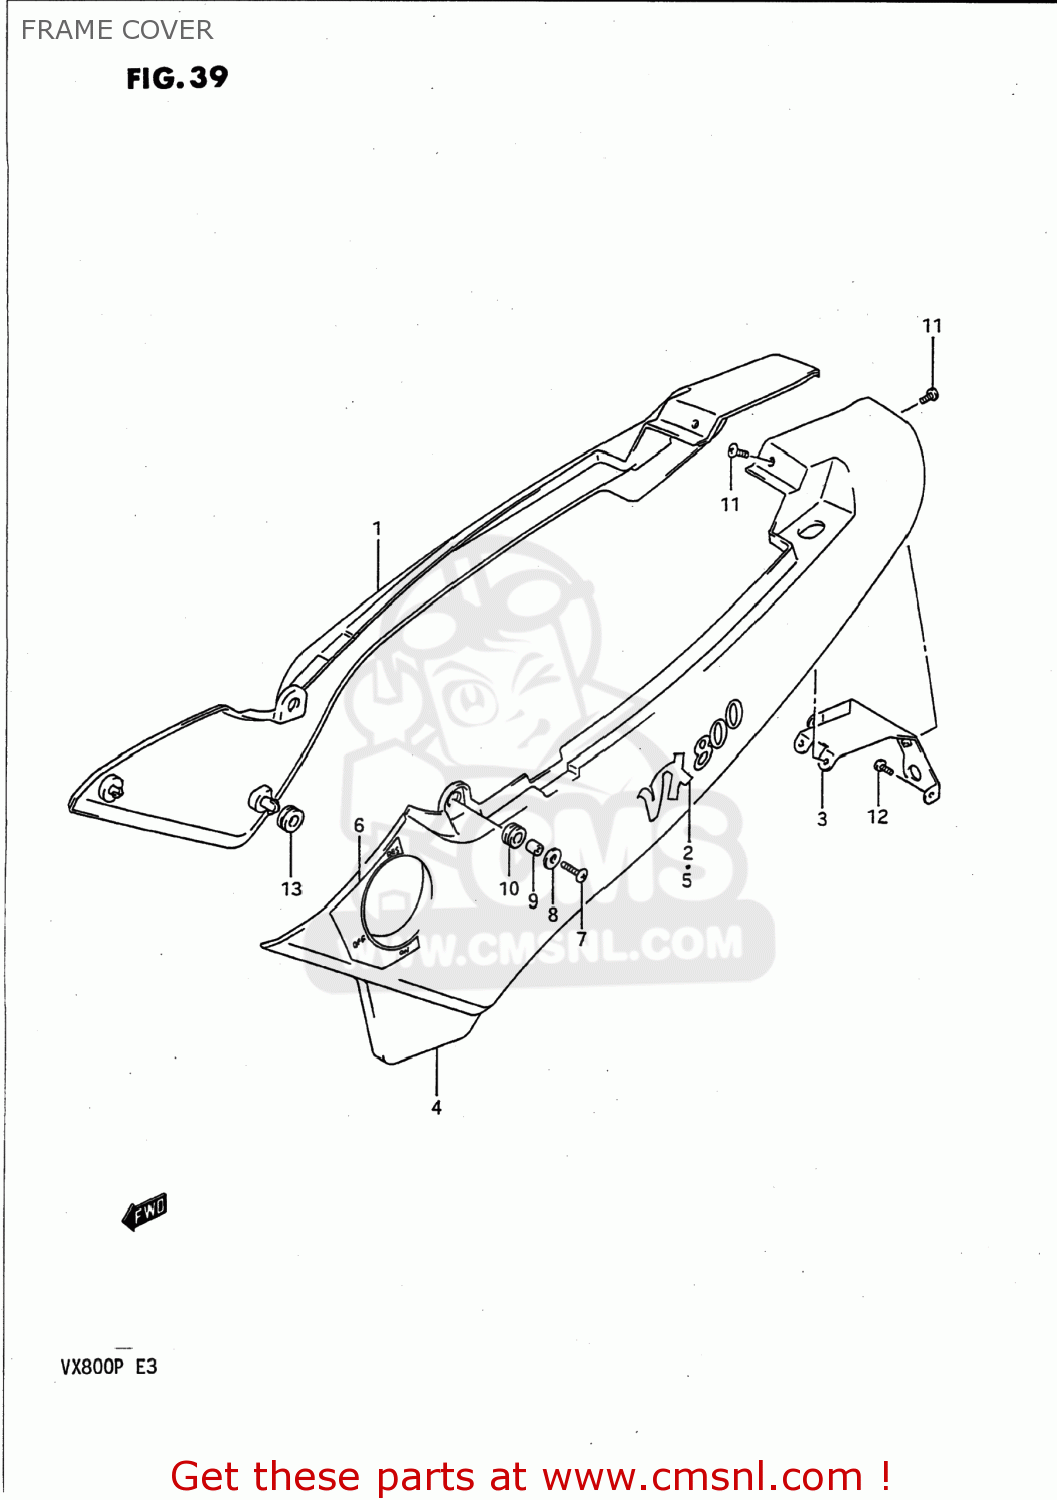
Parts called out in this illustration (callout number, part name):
1	COVER,FRAME,RIGHT
2	EMBLEM,FRAME COVER
3	BRACKET COMP,FRAME COVER
4	COVER,FRAME,LEFT
5	EMBLEM,FRAME COVER
6	LABEL,FUEL COCK
7	SCREW, CENTER
8	WASHER(6.5X18X1)
9	SPACER
10	CUSHION
11	SCREW
12	SCREW
13	CUSHION
